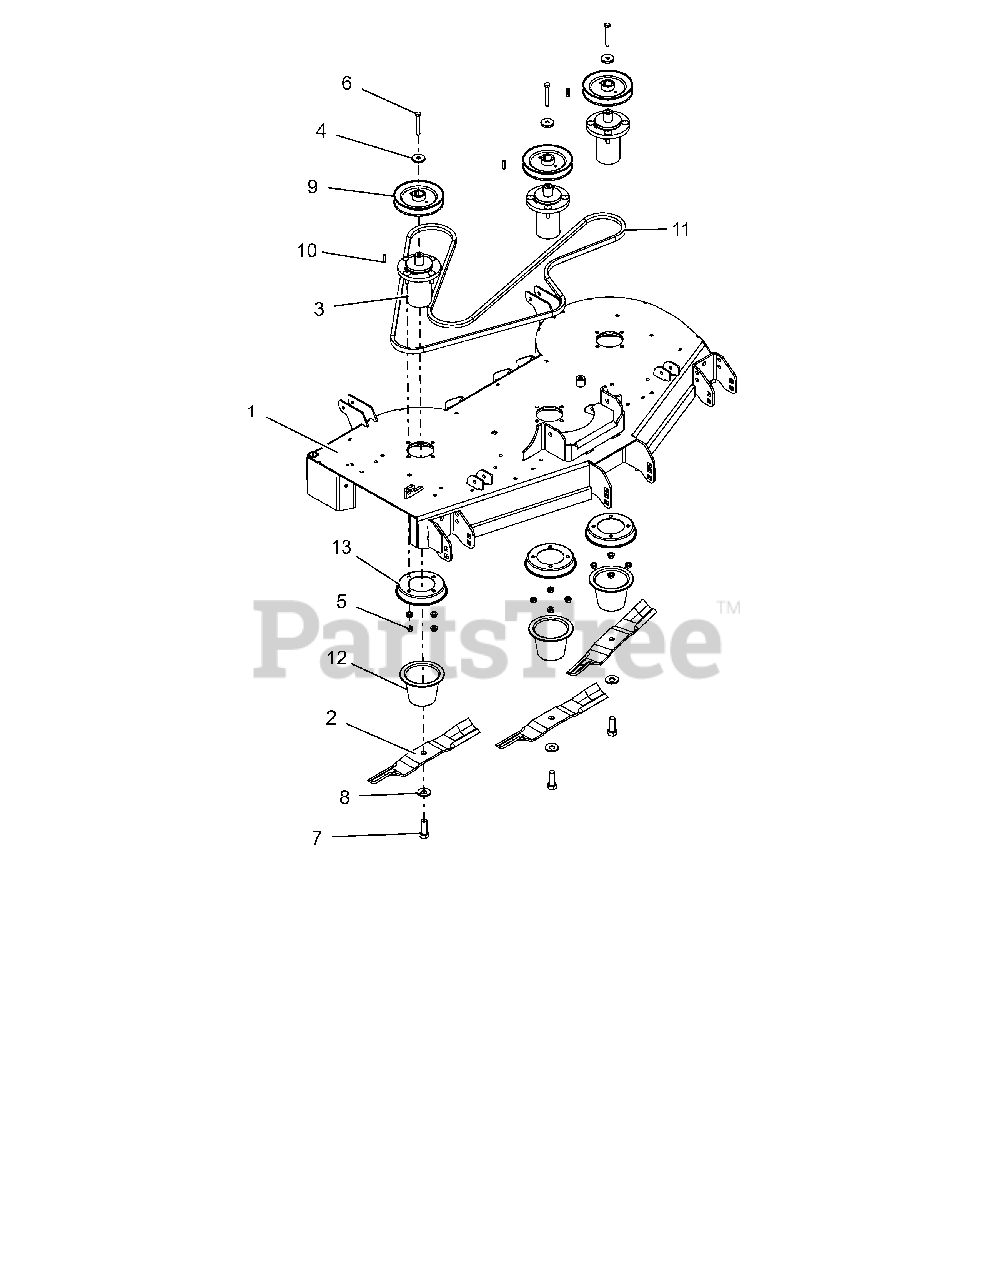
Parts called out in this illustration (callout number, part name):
1	KIT, 48" MOWER DECK W DECALS
2	BLADE, 16.19" MOWER (HI-LIFT)
3	ASM, MAINT FREE ALUM SPINDLE
4	RETAINER, SHEAVE
5	NUT-LK-CTR-FLG .38-16 YWZC
6	BLT-HEX .38-16X2.75 GR8 YWZC
8	WSHR-BLVL .669X1.535X.138
9	PULLEY, 1.00 ID X 5.75 OD
10	KEY, SQ .25X.25X1.00 RC 40-50
11	BELT, B-SECTI0N EPDM RAW EDGE
12	GUARD, SPINDLE LOWER
13	GUARD, SPINDLE TOP
